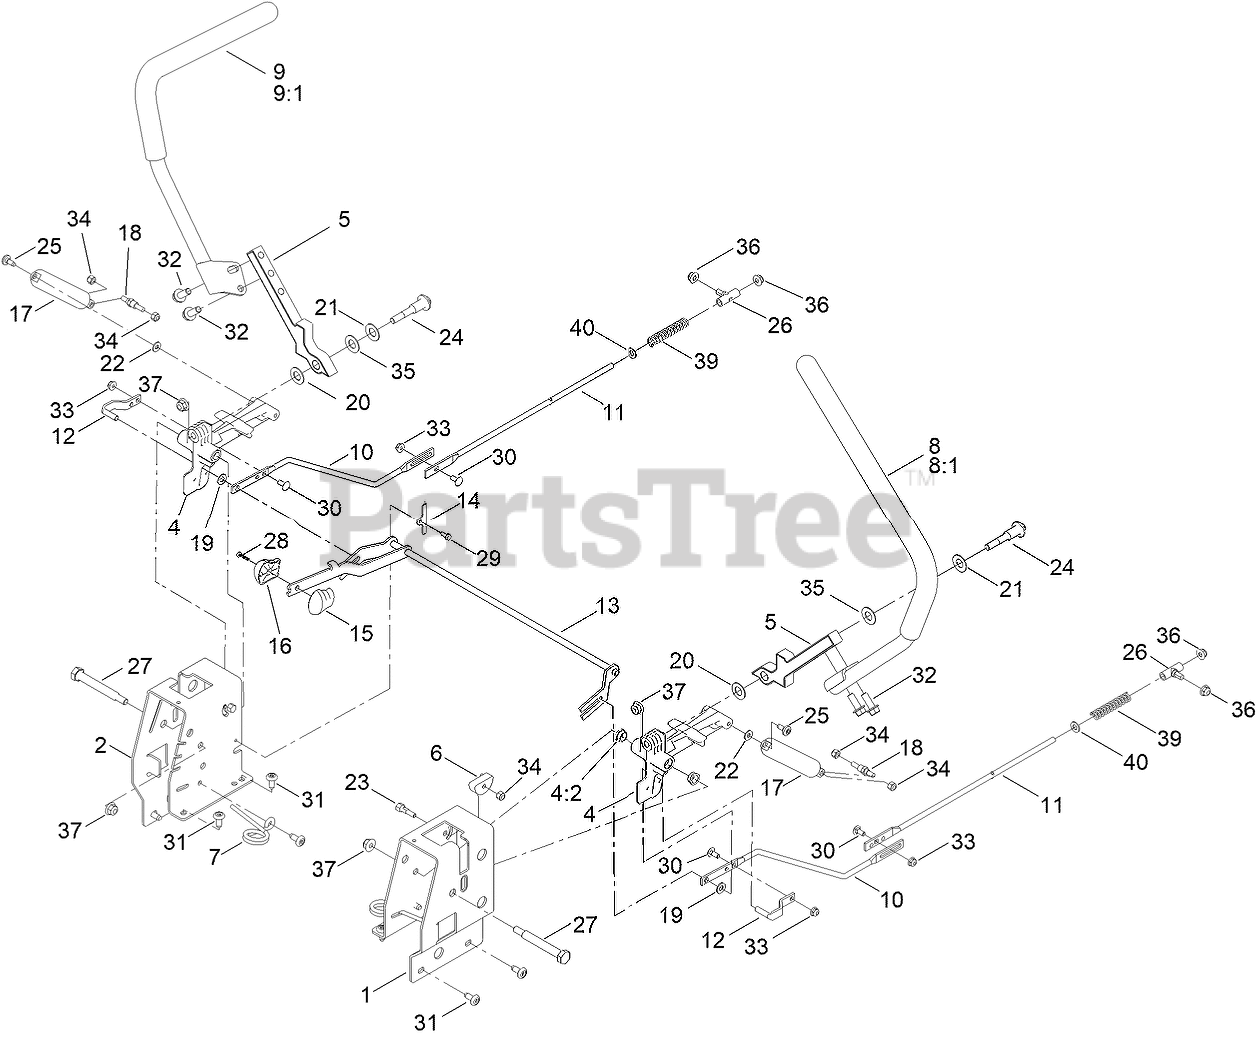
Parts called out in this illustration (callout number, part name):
1	PLATE-CONTROL BOX, LH
2	PLATE-CONTROL BOX, RH
4	ACTUATOR ARM ASM
4:2	BUSHING-FLANGE
5	ARM-CONTROL
6	ECCENTRIC
7	SPRING-TORSION
8	HANDLE-CONTROL, LH
9	HANDLE-CONTROL, RH
10	ROD-HYDRO, FRONT
11	ROD-HYDRO, REAR
12	PIN-ROD, HYDRO
13	SPEED CONTROL ASM
14	PLATE-RETAINER
15	KNOB-RH
16	KNOB-LH
17	DAMPER-NON CAVITATING
18	STUD-DAMPER
19	SPACER-NYLON
20	WASHER-NYLON
21	WASHER-BELLEVILLE
22	WASHER
23	BOLT-PIVOT, ECCENTRIC
24	BOLT-PIVOT
25	SCREW-SHOULDER
26	MOUNT-ROD, HYDRO
27	BOLT-PIVOT
28	SCREW-PPH
29	SCREW-TAPTITE
30	SCREW-CARR
32	SCREW-HHF
33	NUT-HF
34	NUT-LOCK, NI
35	WASHER
36	NUT-HF
37	NUT-HF, NI
39	SPRING-COMPRESSION
40	WASHER-PLAIN
